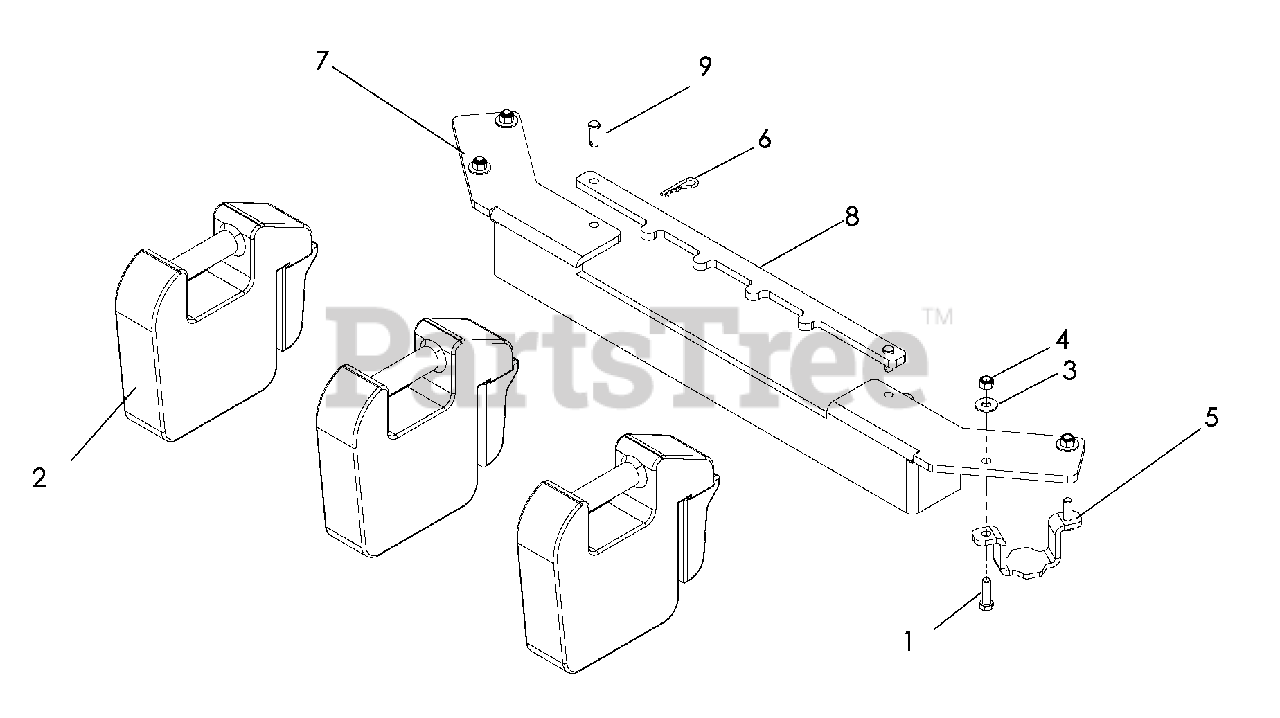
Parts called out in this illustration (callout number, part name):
1	HCS 3/8-16 x 1¼
2	CAST COUNTERWEIGHT
3	WASHER 3/8
4	NUT 3/8-16 NYLOC
5	WEIGHT KEEPER
7	WEIGHT BAR, FRONT
8	HOLD DOWN, WEIGHT BAR
9	CLEVIS PIN
